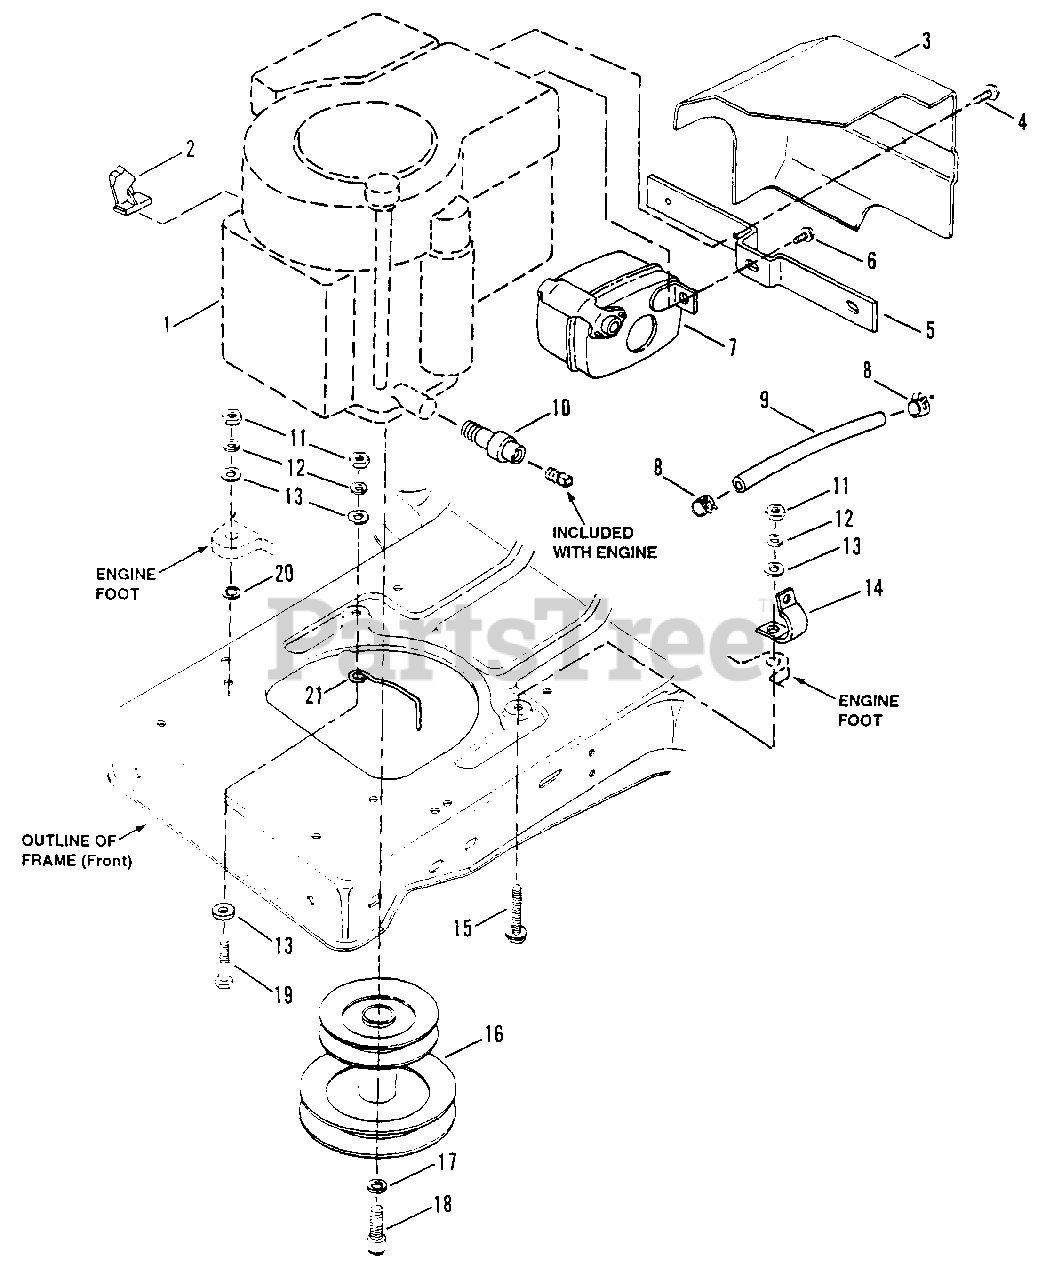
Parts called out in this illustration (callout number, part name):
2	CLIP, Speed
3	HEAT SHIELD
4	SCREW, #10-24 x 1/2" H.W.H.S.T.
5	BRACKET, Heat Shield
6	BOLT, 1/4-20 x 1/2" Hex Flange Lock
7	MUFFLER, Exhaust
8	CLAMP, Fuel Line
9	LINE, Fuel, 7" Long
10	EXTENSION, Oil Drain (Short)
11	NUT, 5/16-18 Hex
12	WASHER, 5/16 Split Lock
13	WASHER, 5/16 Flat
14	CLIP, Harness
15	SCREW, 5/16-18 x 1 1/2" H.H.C.
16	PULLEY ASSEMBLY
17	WASHER, 7/16 Split Lock
18	SCREW, 7/16-20 x 1" H.C., Sk. Hd.
19	SCREW, 5/16-18 x 1 3/4" H.H.Cap
20	WASHER, 5/16 Internal Tooth Lock
21	GUIDE, Belt
